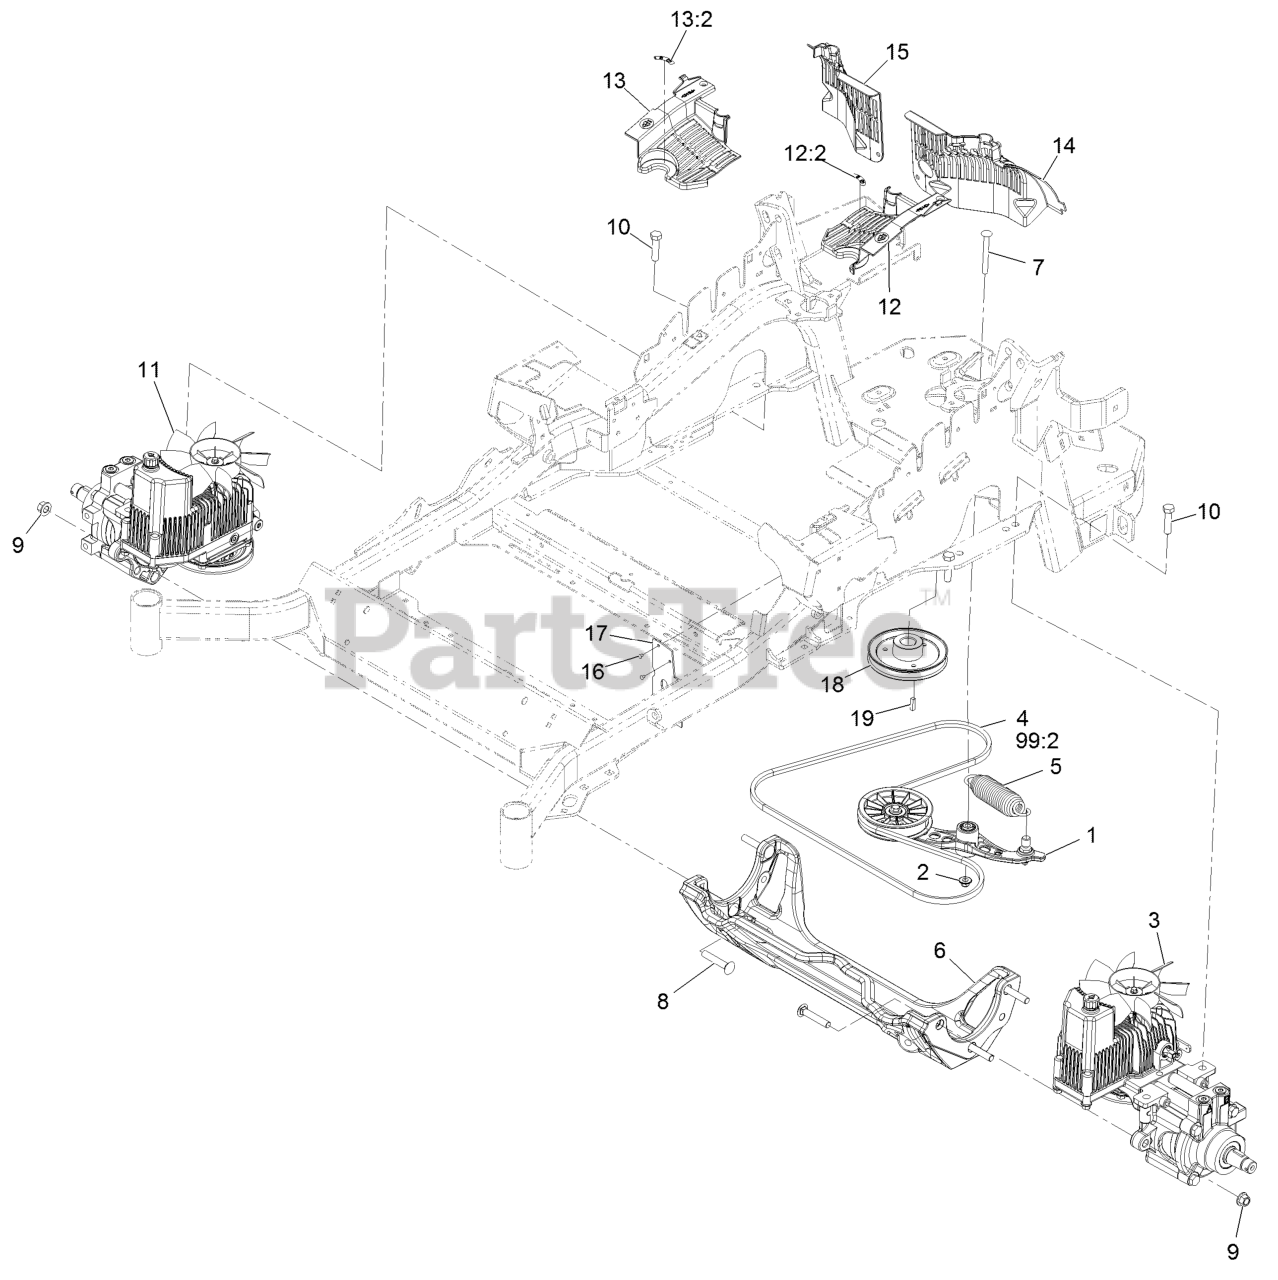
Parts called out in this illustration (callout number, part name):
1	Pump Idler ASM
2	Nut-Nyloc 3/8-16 Flg
3	LH Hydro ASM (12Cc W/ Shock)
4	Belt
5	Spring-Extension
6	Cradle-Hydro
7	Bolt-Carriage Shoulder 3/8-16 X 3 1/2
8	Screw-CARR
9	Nut-Lock 1/2-13
10	Screw-HH 1/2-13 X 1 1/4
11	RH Hydro ASM (12Cc W/ Shock)
12	LH Hydro Guard ASM
12:2	Decal-Oil, Hydro
13	RH Hydro Guard ASM
13:2	Decal-Oil, Hydro
14	Guard-Hydro, Rear (LH)
15	Guard-Hydro, Rear (RH)
16	Rivet 3/16 X 1/4
17	Deflector-Air Flow
18	Sheave
19	Key-Machine 1/4 X 1/4 X 1
99	Bottle-Oil, 32Oz Hydraulic
99	Filter-Hydro
99	Bottle,Oil 1 Gallon Hydraulic
99	Kit, Hydro Service
99:1	Bottle-Oil, 32Oz Hydraulic
99:2	Belt
99:3	Filter-Hydro
